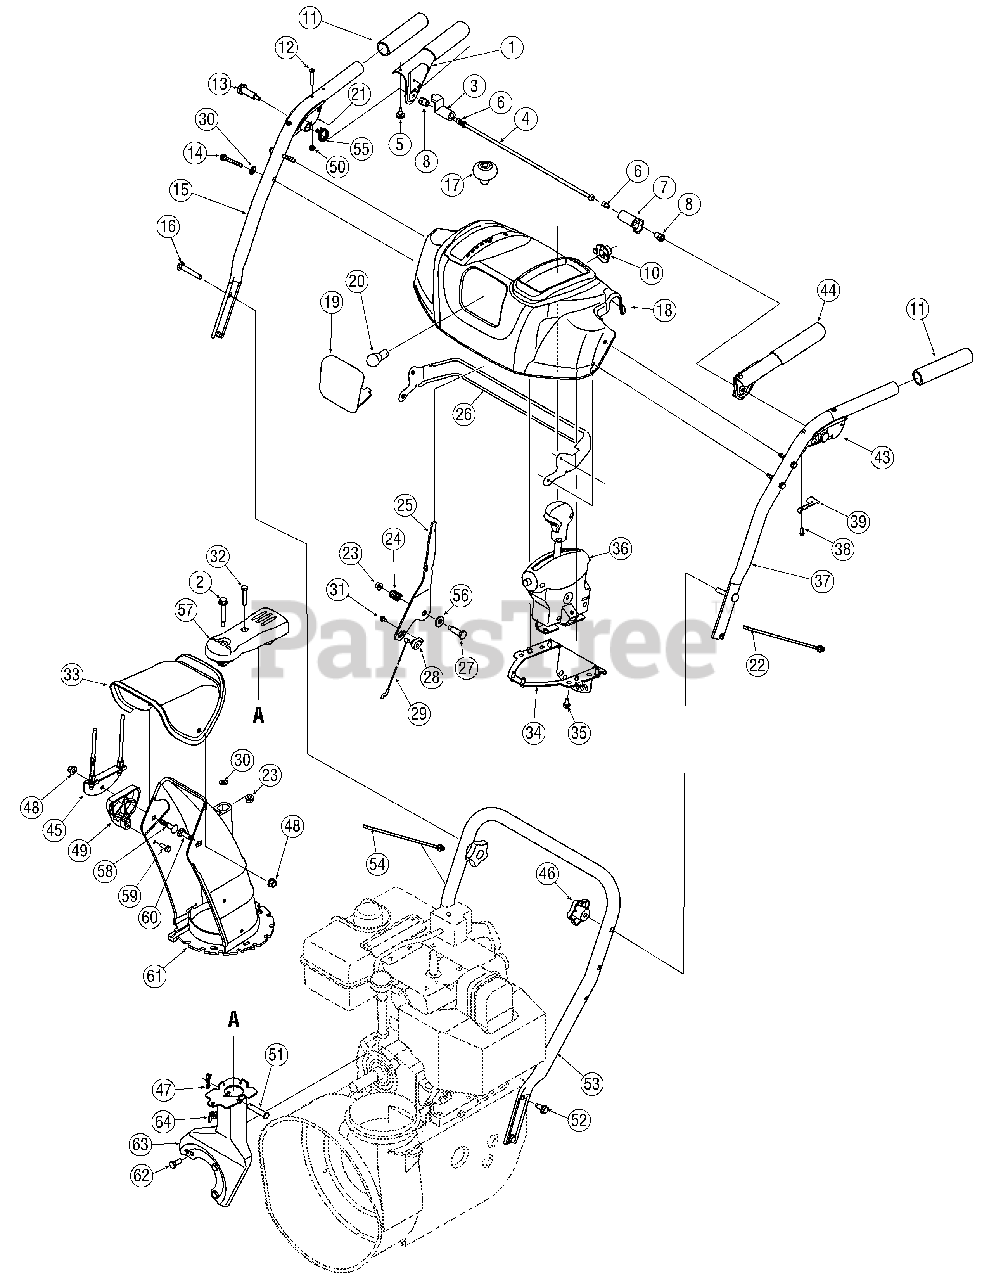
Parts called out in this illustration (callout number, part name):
1	Handle Engagement Assembly RH
2	Flange Shoulder Screw
3	Lock Plate
4	Pivot Rod
5	Rubber Bumper
6	Screw, 1/4-20 x.375
7	Clutch Lock Cam
8	Shoulder Nut, 1/4-20
9	Wire Harness
10	Light Socket
11	Handle Grip
12	Screw, #10-24 x 0.375
13	Shoulder Screw, 1/4-20 x 1.345
14	Screw, 1/4-20 x 1.750
16	Carriage Screw, 5/16-18 x 2.25
17	Shift Knob
18	Handle Panel, K/L-Style, Black
21	Handle Clutch Lock - RH
22	Cable Tie
23	Flange Lock Nut, 1/4-20
24	Compression Spring
25	Shift Lever
26	Panel Bracket
27	Shoulder Screw
28	Cable Barrel Holder
29	Speed Selector Cable
30	Flat Washer, .25 x .630 x .0515
31	Screw, #10-16 x .500
32	Hex Screw, 1/4-20 x 1.50
33	Upper Chute
34	Joystick Bracket
35	Hi-Lo Screw, 1/4-15 x 0.5
36	4 Way Chute Control Assembly Service Kit
38	Screw, #8-16 x 0.50
39	Clutch Lock Spring
40	Steering Control
41	Pin, 3/16
42	E Ring
43	Handle Clutch Lock - LH
44	Handle Engagement Assembly LH
46	Handle Knob Assembly
47	Bow Tie Cotter Pin
48	Flange Lock Nut, 5/16-18
49	Chute Tilt Cable Guide
50	Hex Lock Nut, #10-24
51	Clevis Pin
52	AB Screw, 5/16-18 x 0.75
54	Cable Tie
55	Torsion Spring
56	Flat Washer
57	Joystick Pulley Cover
58	Carriage Bolt, 5/16-18 x 1.50
59	Hi-Lo Screw, 1/4-15 x .75
60	Carriage Bolt, 5/16-18 x 1.0
61	Lower Chute
62	Hex Screw, 5/16-24 x .750
63	Support Bracket
64	Wing Nut, 1/4-20
